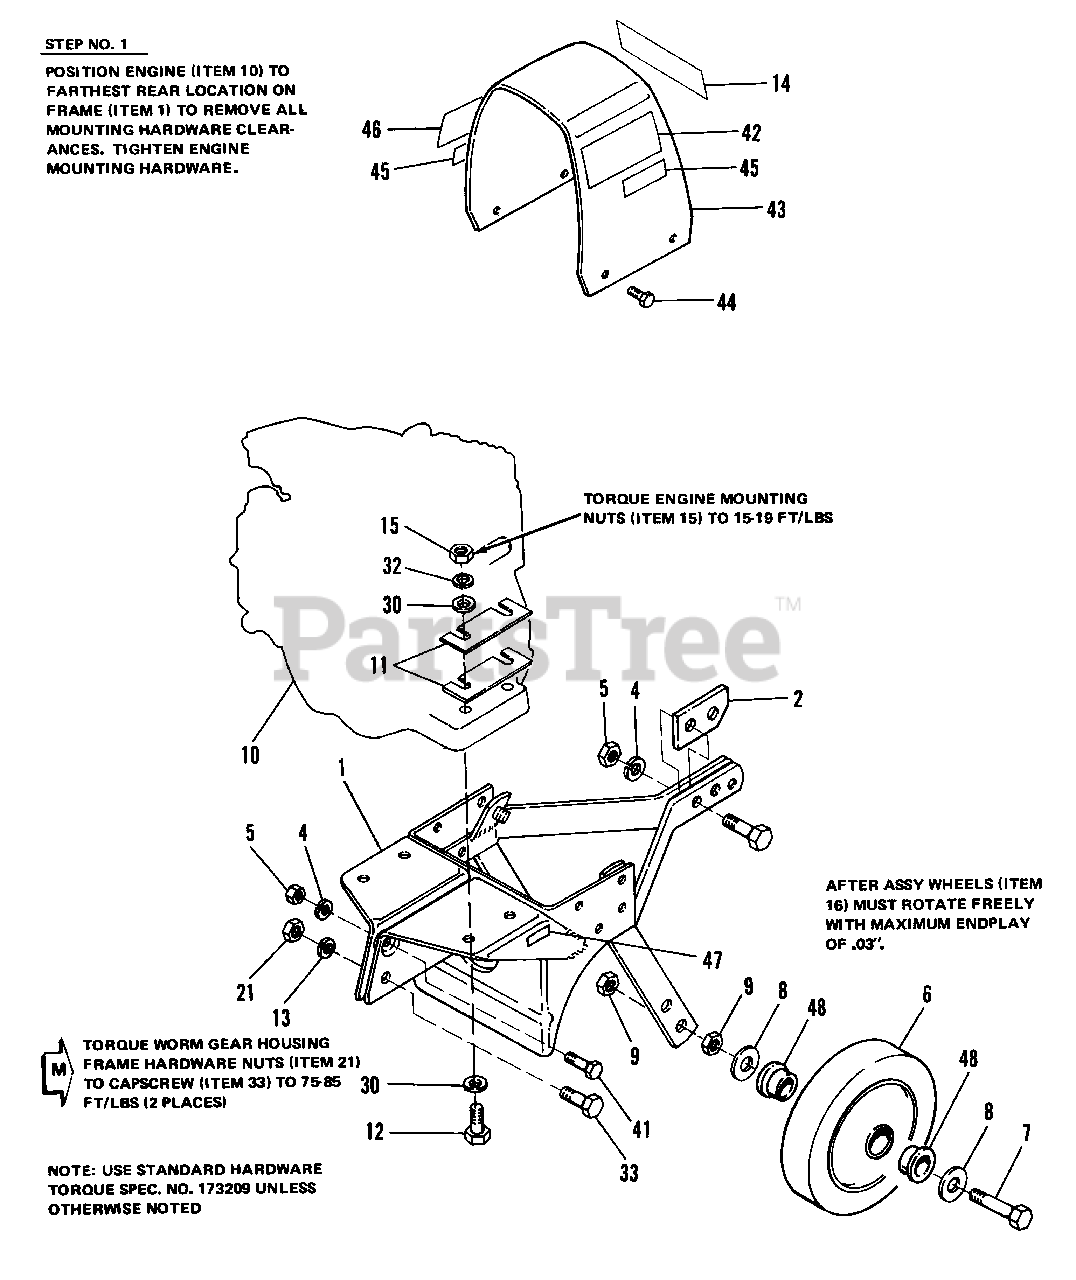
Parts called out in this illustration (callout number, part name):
1	FRAME ASSY
2	STOP, Plate
3	CAPSCREW, Hex, 3/8-16 x 1-1/2
4	LOCKWASHER, 3/8
5	NUT, Hex, Full, 3/8-16
6	WHEEL & TIRE ASSY
7	CAPSCREW, Hex, 1/2-13 x 3-1/2
8	WASHER, Plain, 1/2
9	NUT, Hex, Jam, 1/2-13
10	ENGINE, 3 H.P. (Briggs & Stratton)
12	CAPSCREW, Hex Hd., 5/16-18 x 1-3/4
13	LOCKWASHER, 7/16
14	DECAL, Simplicity
15	NUT, Hex, 5/16-18
16	PULLEY, Engine, Forward
17	KEY, Sq., 3/16 x 1
18	SCREW, Set, 5/16-18 x 5/16
20	LOCKWASHER, 1/2, Int. Tooth
21	NUT, Hex, Full. 7/16-20
22	PULLEY, Worm Gear
24	CAPSCREW, Hex, 1/2-20 x 1
25	BELT, Forward
26	LEVER, Idler Pulley
27	PULLEY, Idler, Forward
29	CAPSCREW, Hex, 3/8-16 x 1-3/4
30	WASHER, Plain, 5/16
31	STOP, Belt
32	LOCKWASHER, Spring, 5/16
33	CAPSCREW, Hex, 7/16-20 x 1-1/4
34	LOCKNUT, Hex, Jam, 3/8-16
35	BOLT, Pivot
36	LOCKNUT, Flange, Whiz
37	BELLCRANK
38	LINK, Rod
39	PIN, Cotter, 1/16 x 24
40	LOCKNUT, Hex, Flange
41	CAPSCREW, Hex, 3/8-16 x 3/4
42	DECAL, Roticul, L.H.
43	COVER, Engine
44	SCREW, Taptite, 1/4-20 x 3/8
45	DECAL, 1003
46	DECAL, Roticul, R.H.
47	I.D. PLATE
48	BUSHING, Wheel
